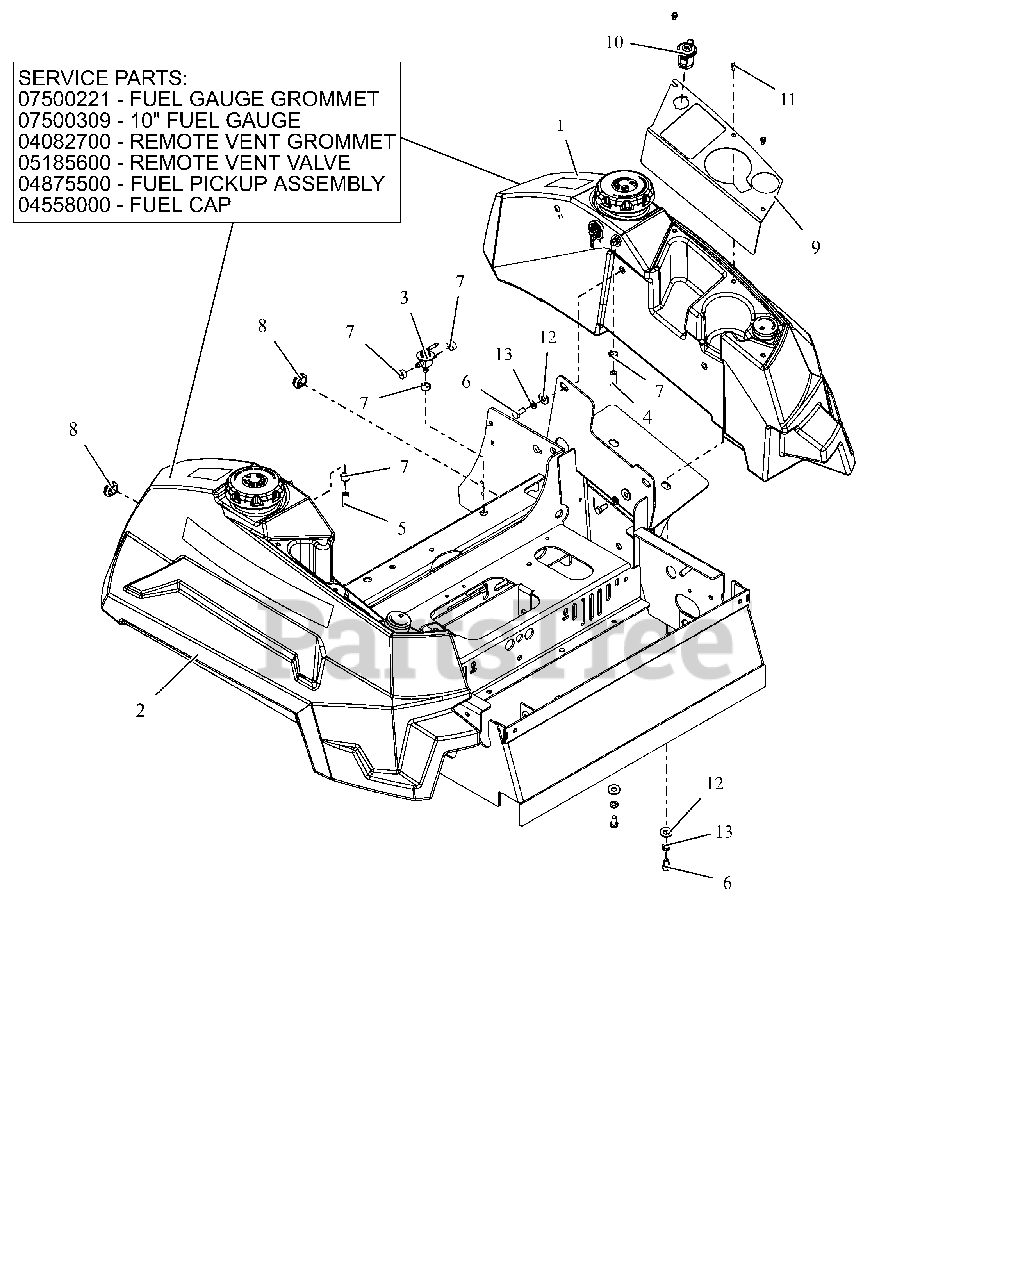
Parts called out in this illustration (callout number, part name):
1	ASM, LH FUEL TANK
2	ASSY-RH, PT400 FUEL TANK
2	GROMMET, FUEL GAUGE
2	GAUGE, REMOTE FUEL SEALED 10"
2	GROMMET, REMOTE VENT NITRILE
2	VALVE, COMBINATION VENT 3/16
2	ASSM,LRG TANK FUEL PICKUP LINE
2	CAP, FUEL VENTIN AUTOLOCK
3	VALVE - FUEL
4	HOSE, .25 LOW-PERM BULK GAS
5	HOSE, .25 LOW-PERM BULK GAS
6	@BLT-HEX .31-18X.75 GR5 YWZC
7	CLAMP, FUEL LINE
8	GROMMET,RUBBER 5/8 ID/1.13 OD
9	CUP HOLDER/POCKET PLATE - RED
10	PORT, 12 VOLT POWER
11	SCR-MCH 10-24X.38 HWHSTAINLESS
12	@WSHR-FL-STL.38X.875X.083 YWZC
13	@WSHR-LK .31X.078 REG YWZC
